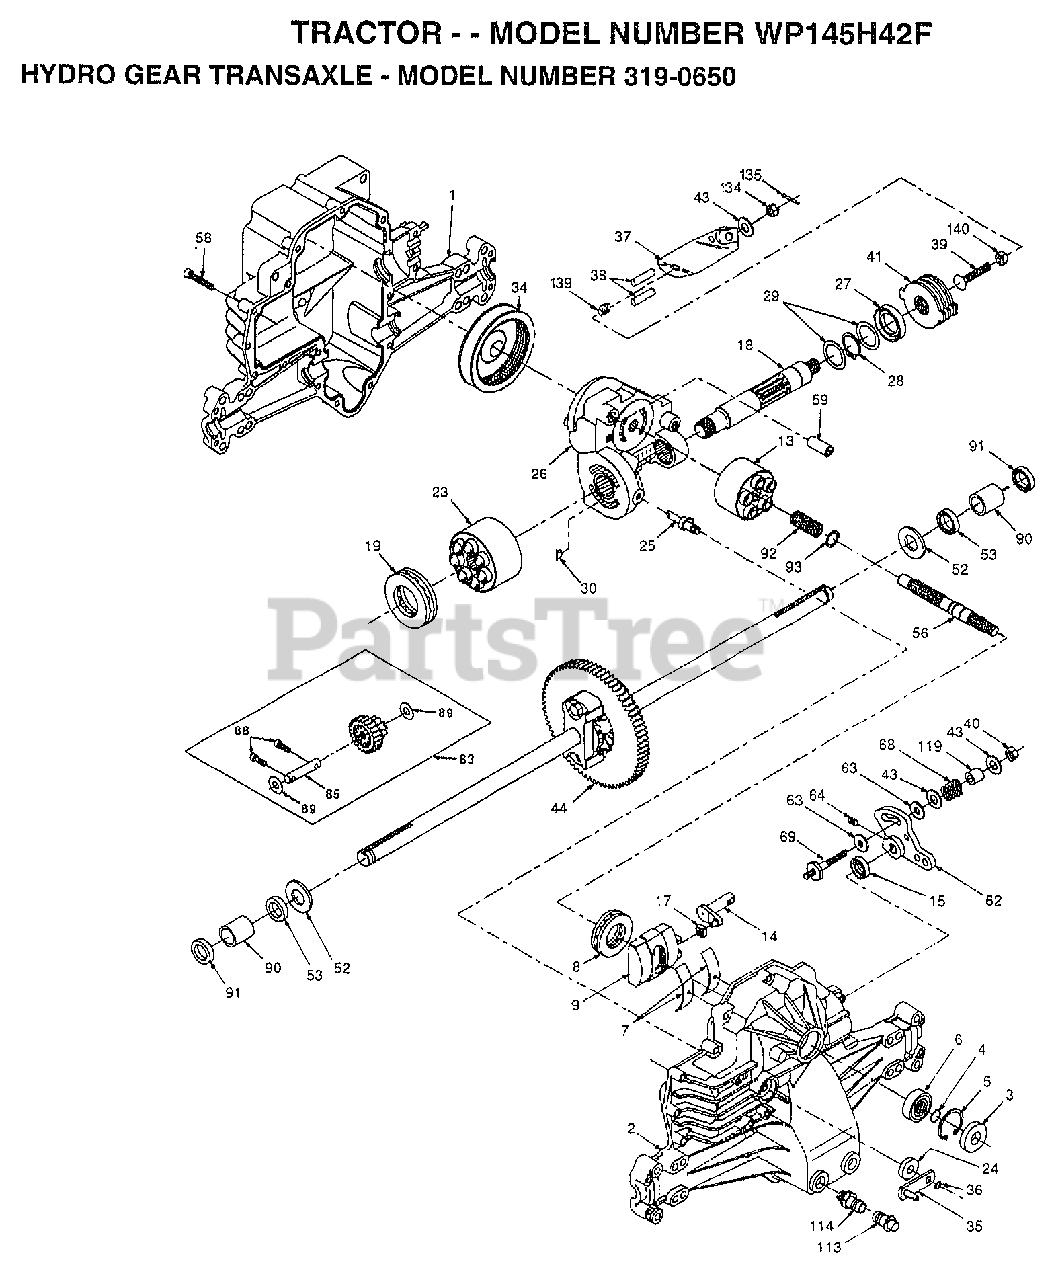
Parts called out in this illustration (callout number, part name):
1	HOUSING.L.50074RM
2	HOUSING.UP.70125
3	SEAL.9008000-0128
4	RING.RET.2003016.
5	RING.RET.2003052.
6	BEARING.(50552)42X68X16
7	CRADLE- 2003023.
8	BEARING.THU.50551
9	SWASHPLT.2003087.
13	BLOCK.CLYN.70079.
14	ARM.TRUN.2003005.
15	SEAL.9008000-0126
17	GUIDE.2000015.
18	SHAFT.MOTOR.50449
19	BEARING.THU.50552
23	BLOCK.CYLIN.70082
24	SEAL.LIP.45074
25	ACTUATOR.2003555
26	KIT.CEN.SEC.70250
27	SEAL.LIP.45075
28	RING RETAIN 50007
29	WASHER.44872
34	ELEMENT.OIL.44964
35	ARM.BYPASS.50270
36	RING.RETAIN.44870
37	ARM.ACTUAT.23710
38	PIN.ACTUAT.44891
39	BOLT.50316
40	NUT.LOCK.HX.50317
41	KIT.BRAKE.70135
43	WASHER HYD 44130
44	DIFFRENTIAL.70226
52	WASHER.HYD.44875
53	SEAL.HYDRO.45076
56	SHAFT.INPUT.50005
58	BOLT.1/4-20.44876
59	PIN.HYDRO.50002
62	ARM.CONTROL.50254
63	PUCK.DAMPER.50281
64	SCREW.SET.50018.
68	SPRING.HYD.50277
69	STUD.5/16-24.DANA
83	JACKSHAFT/PINION GEAR.70132
85	PIN.SHAFT 50559
88	SCREW.CAP.50154.
89	WASHER.HYD.50132
90	BEARING.SLV.50118
91	SEAL.WIPER.50941
92	SPRING.2003014.
93	WASHER.2003017
113	CAP.VENT.70109
114	O-RING.ASM.70110
119	SPACER.HYD.50278
134	NUT.CAS.HYD.44142
135	PIN.COT.HYD.44101
139	SPRING.COMP.50431
140	NUT.HEX.50269
